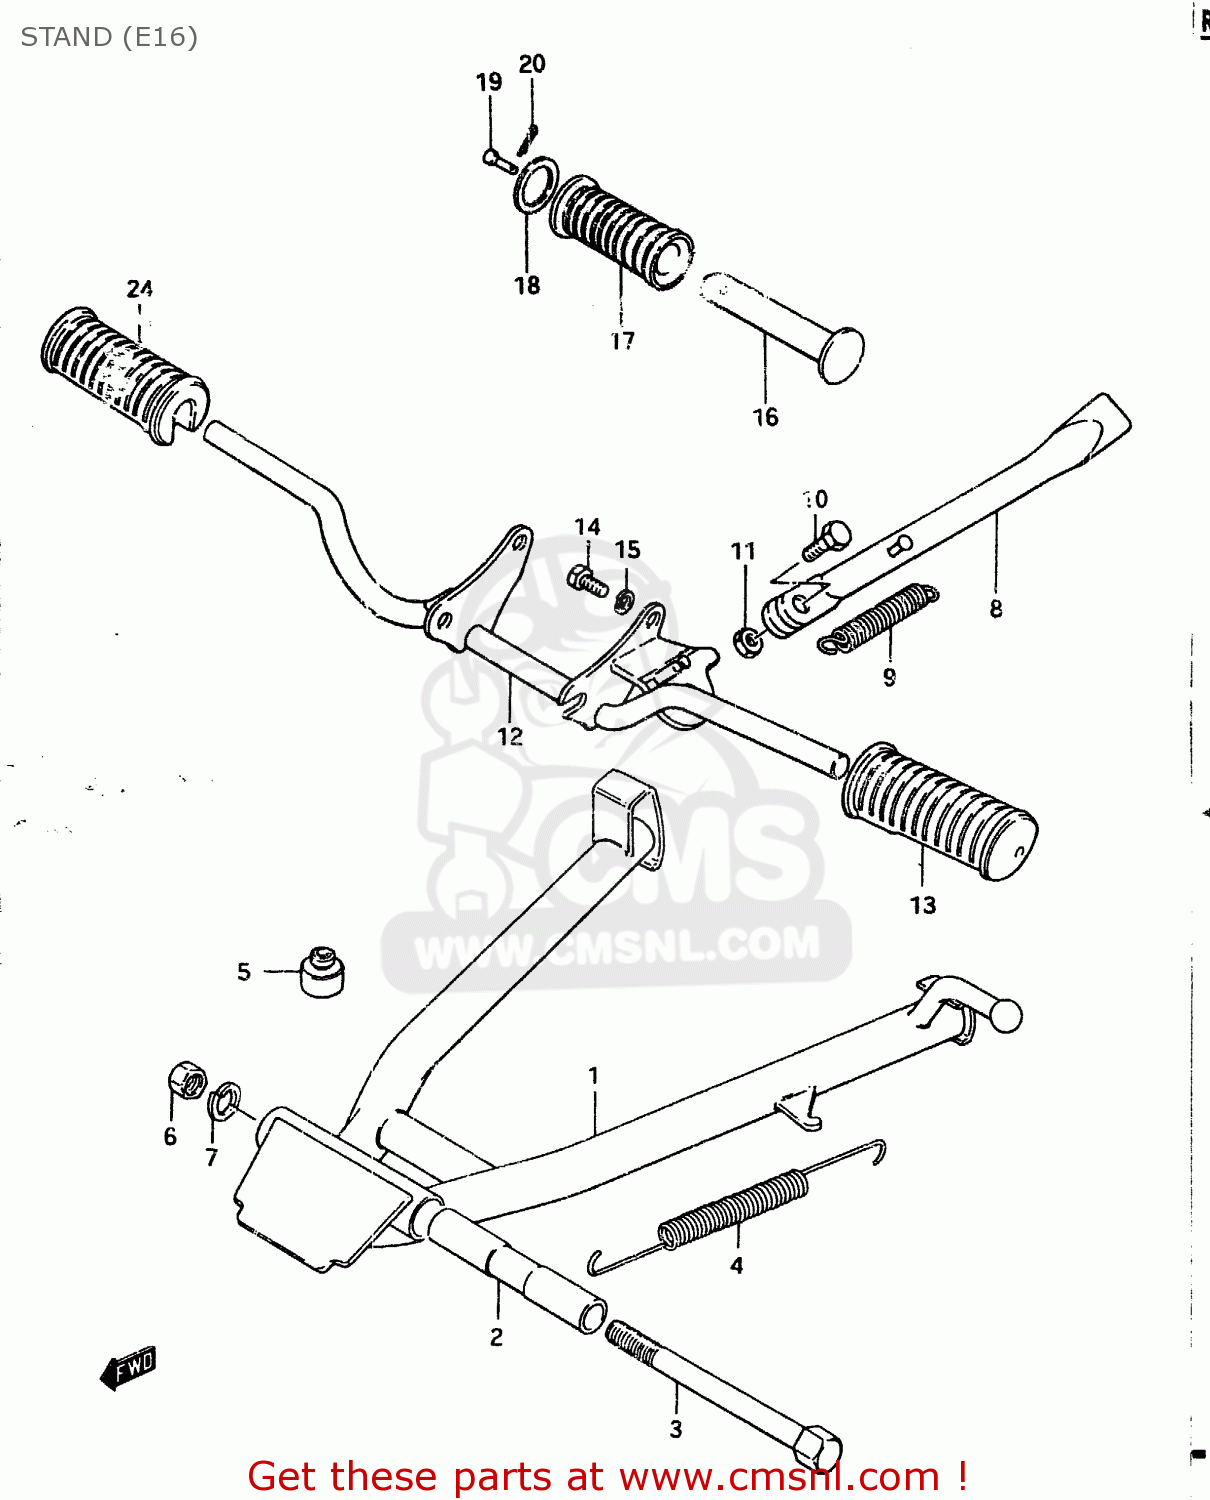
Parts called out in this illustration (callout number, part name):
1	STAND, CENTER
2	SPACER
3	BOLT(10X110)
4	SPRING
5	CUSHION
6	NUT
7	LOCK WASHER
8	STAND, PROP
9	SPRING
10	BOLT(10X28)
11	NUT
12	BAR, FRONT FOOTREST
13	RUBBER,FR FOOTREST
14	BOLT
15	LOCK WASHER
16	BAR,FOOTREST RUBBER
17	RUBBER,PILLION FOOTREST
18	WASHER (19.5X32X2)
19	PIN
20	PIN 20X20
